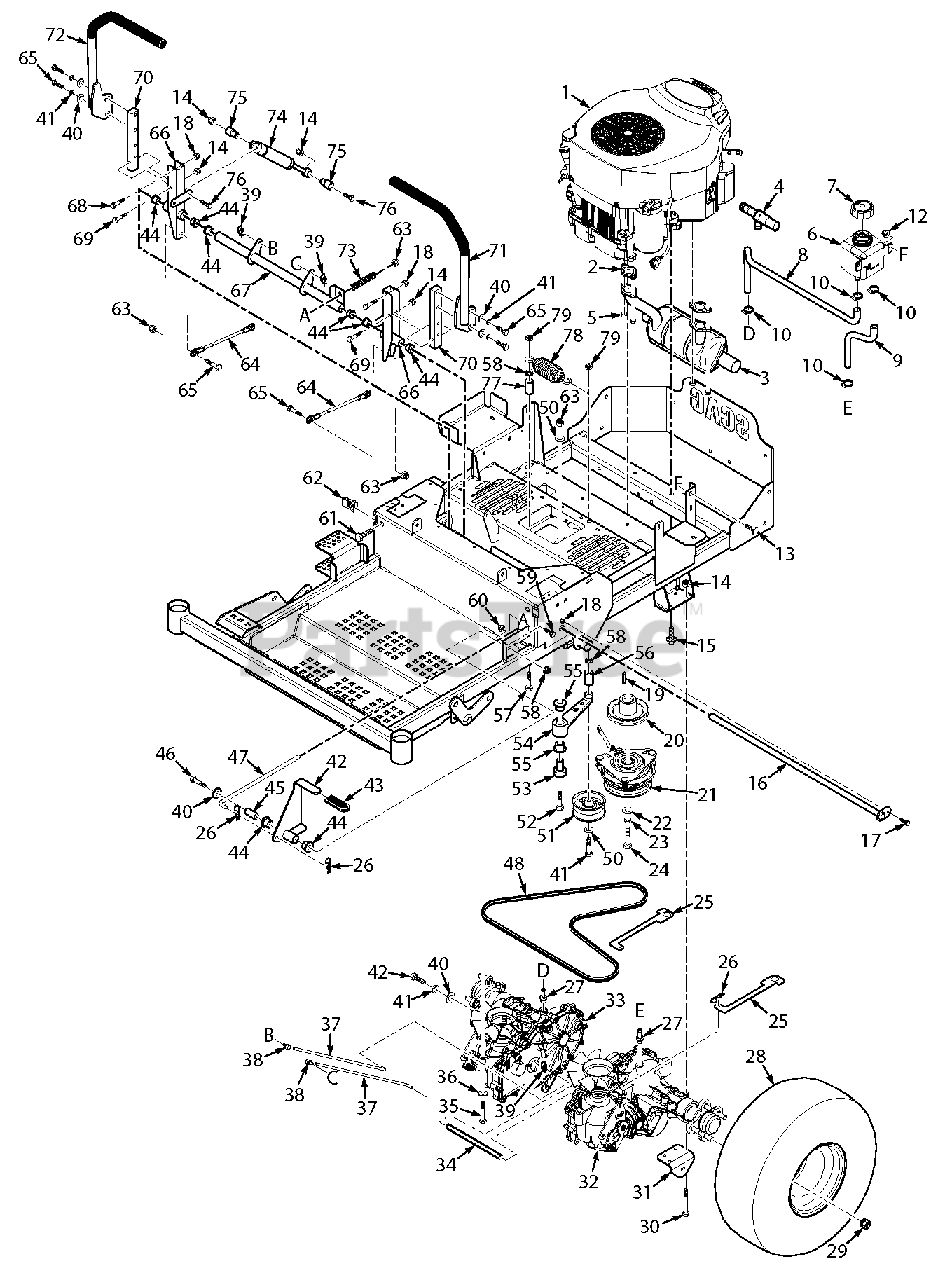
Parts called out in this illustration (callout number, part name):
1	Engine, Kohler - 22KT
1	Engine, Kohler - 24KT
2	Gasket, Exhaust
3	Muffler, Kohler KT
4	Oil Drain
5	Nut, M6-1.0 Hex Flange
6	Reservoir Assembly
8	Hose, RH Transmission
9	Hose, LH Transmission
10	Clamp, .87 Max. Dia.
11	Clamp, .69 Max. Dia.
12	Nut, 1/4-20 Flange Elastic Stop
13	Bolt, Carriage 1/4-20 x 3/4"
14	Nut, 5/16-18 Elastic Stop
15	Bolt, 3/8-16 x 1-1/4" Serrated Flange Self Tap
16	Shaft Weldment, Control Arm
17	Bolt, Hex Head 1/4-20 x 5/8"
18	Nut, 1/4-20 Elastic Stop
19	Key, 1/4 x 1/4 x 1-1/4"
20	Pulley, 4-1/2" - 1" Bore
21	Clutch, GT1
22	Flatwasher, 7/16-.496 x 1.75 x .25
23	Lockwasher, 7/16"
24	Bolt, 7/16-20 x 3" w/Patch
25	Lever, Dump Valve
26	Hair Pin Cotter, .080 x 1.19
27	Fitting, O-Ring x 3/8" Hose
28	Wheel Assembly
28	Rim w/Valve Stem
28	Tire, 20 x 10-8
29	Wheel Nut, 1/2-20 x 13/16
30	Bolt, Hex Head 5/16-18 x 3"
31	Bracket, Pusharm
32	Transaxle, LH - SZL
33	Transaxle, RH - SZL
34	Spacer
35	Bolt, Hex Head 5/16-18 x 2-1/4"
36	Flatwasher, 5/16-.375 x .875 x .083
37	Rod, Brake
38	Joint, Swivel
39	Pin, Rue Cotter - 3/8"
40	Flatwasher, 3/8-.391 x .938 x .105
41	Lockwasher, 3/8"
42	Brake Lever Assembly
43	Grip, Brake Handle
44	Bearing
45	Pivot, Brake Lever
46	Bolt, Hex Head 3/8-16 x 2-1/2"
47	Rod, Upper Brake Linkage
48	Belt, Transmission -SZL
49	Bolt, Hex Head 3/8-16 x 3-3/4"
50	Flatwasher, 3/8-.391 x .938 x .105 HD
51	Pulley, 3-1/2" Idler
52	Bolt, Hex Head 3/8-16 x 3"
53	Shaft, Pivot Idler Arm
54	Idler Arm Assembly
55	Bearing
56	Spacer, Pump Idler
57	Bolt, Hex Head 3/816 x 2"
58	Nut, 3/8-16 Serrated Flange
59	Bolt, Hex Head 1/4-20 x 1"
60	Nut, 1/4-20 Serrated Flange
61	Bolt, Hex Head 3/8-16 x 2-1/2" Soecial Lock
62	U-Nut, 3/8-16
63	Nut, 3/8-16 Elastic Stop
64	Linkage, Pump
65	Bolt, Hex Head 3/8-16 x 1-1/4"
66	Control Arm Assembly
67	Bellcrank Assembly
68	Bolt, Hex Head 1/4-20 x 1-3/4"
69	Bolt, Hex Head 5/16-18 x 1-3/4"
70	Bar, Control Lever
71	Handlebar w/Grip
71	Grip, Control Lever
72	Handlebar w/Grip
72	Grip, Control Lever
73	Spring, Brake
74	Damper, Steering
75	Spacer, Damper
76	Bolt, Hex Head 5/16-18
77	Spacer
78	Spring, Transmission Drive
79	Nut, 3/8-16 Center Lock
